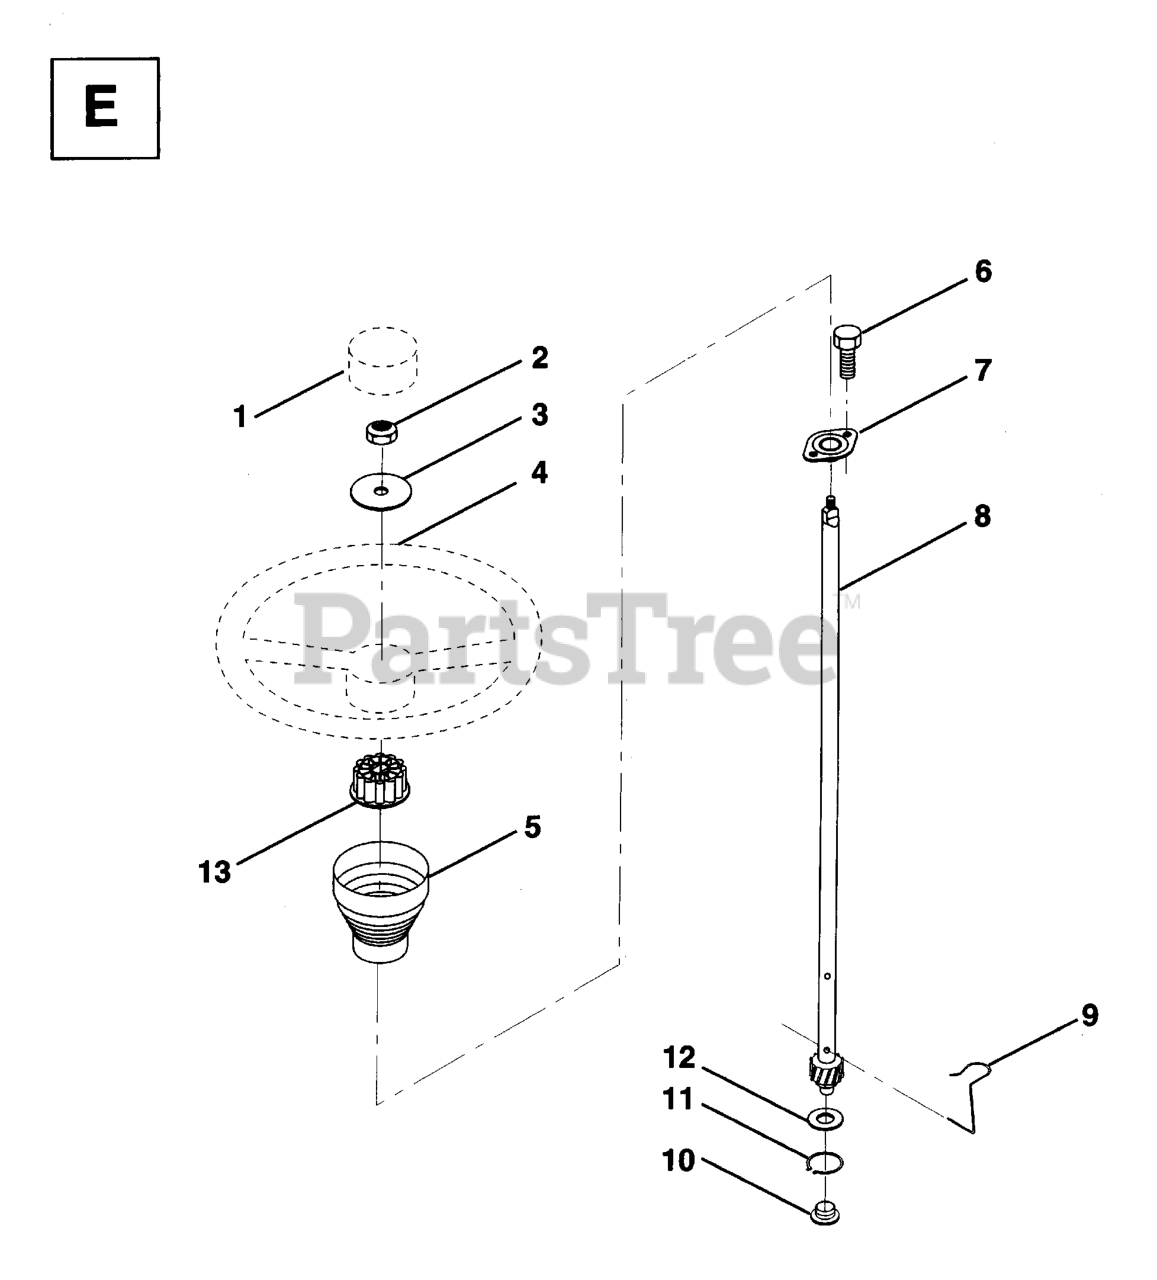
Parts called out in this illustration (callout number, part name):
1	INSERT,STR WHEEL
2	GRIPCO NUT
3	WASHER T
4	STEERING WHEEL
5	STEERING SLEEVE
6	SCREW LT
8	SHAFT STEERING
9	STEERING CLIP
10	BUSHING STEER LWR
13	ADAPTER-WHEEL LT
